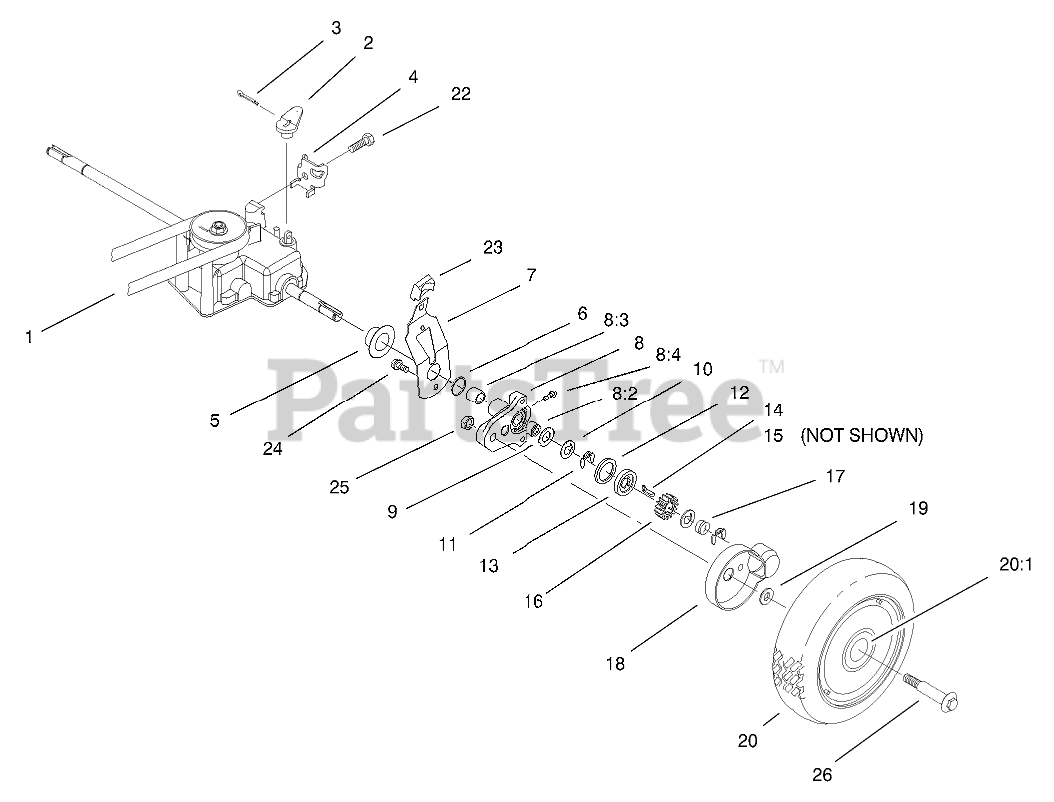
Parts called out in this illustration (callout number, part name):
1	V-BELT E
2	LEVER-SHIFT
3	PIN-COTTER
4	CLAMP-CABLE
5	CAP-END
6	O-RING
7	SPRING ARM ASM
8	PIVOT ARM ASM
8:2	BUSHING
8:3	BUSHING
8:4	FITTING-GREASE
9	WASHER-ARM, PIVOT
10	WASHER-THRUST, KEYED
11	RING-CLIP, LOCKING
12	RING-FRICTION
13	WASHER-CLUTCH
14	KEY-ROCKING, LH
15	KEY-ROCKING, RH
16	GEAR-PINION
17	SPRING-COMPRESSION
18	COVER-WHEEL
19	SPACER-COVER, WHEEL
20	WHEEL ASM
20:1	BUSHING
22	SCREW-HWHTF
23	KNOB-ARM
24	SCREW-HWH
26	BOLT-SHOULDER
